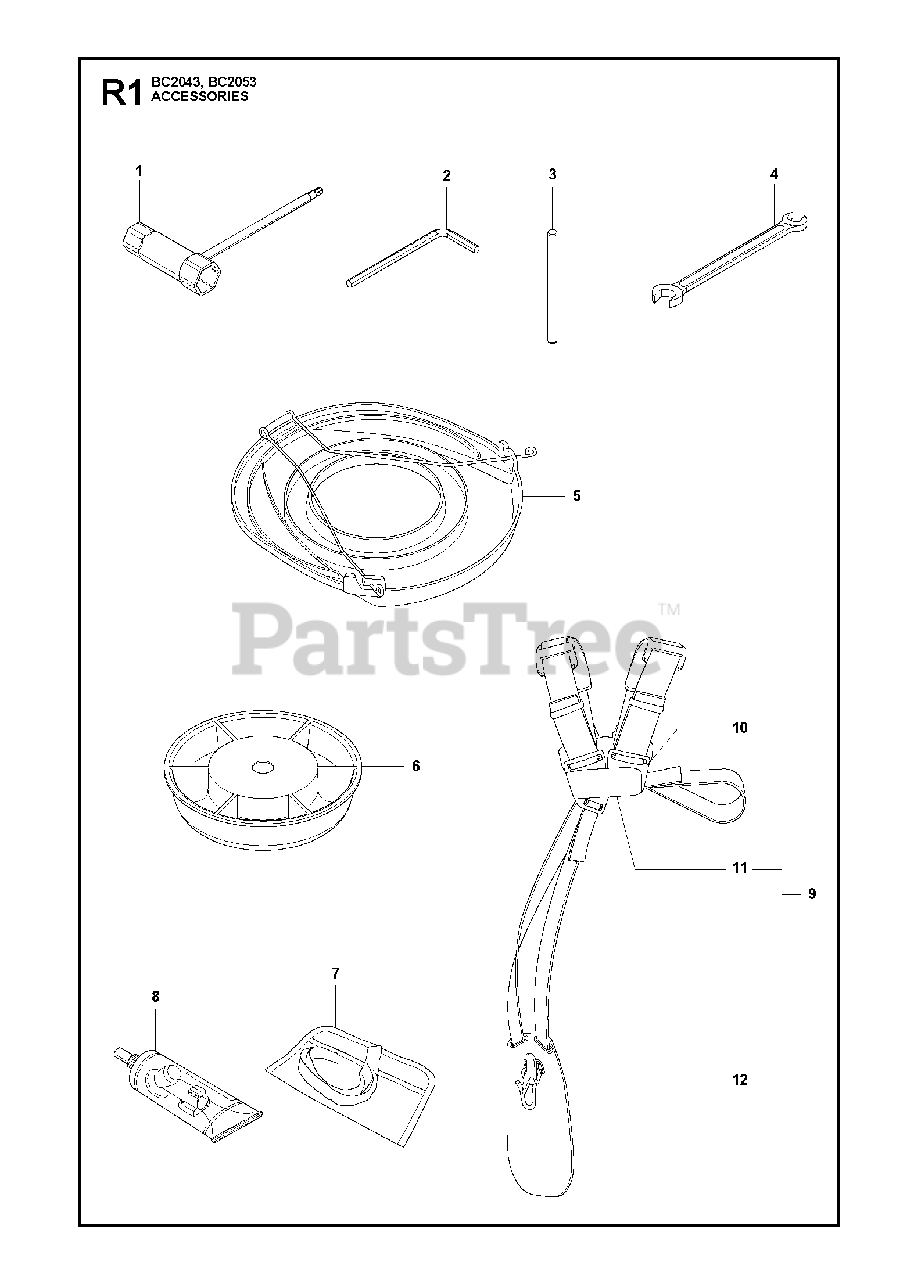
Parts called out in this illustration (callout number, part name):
5	TRANSPORT GUARD
6	SUPPORTING CUP
10	FRONT PIECE
11	FRONTPIECE-RIGHT NLA
12	HOOK, CPL.
